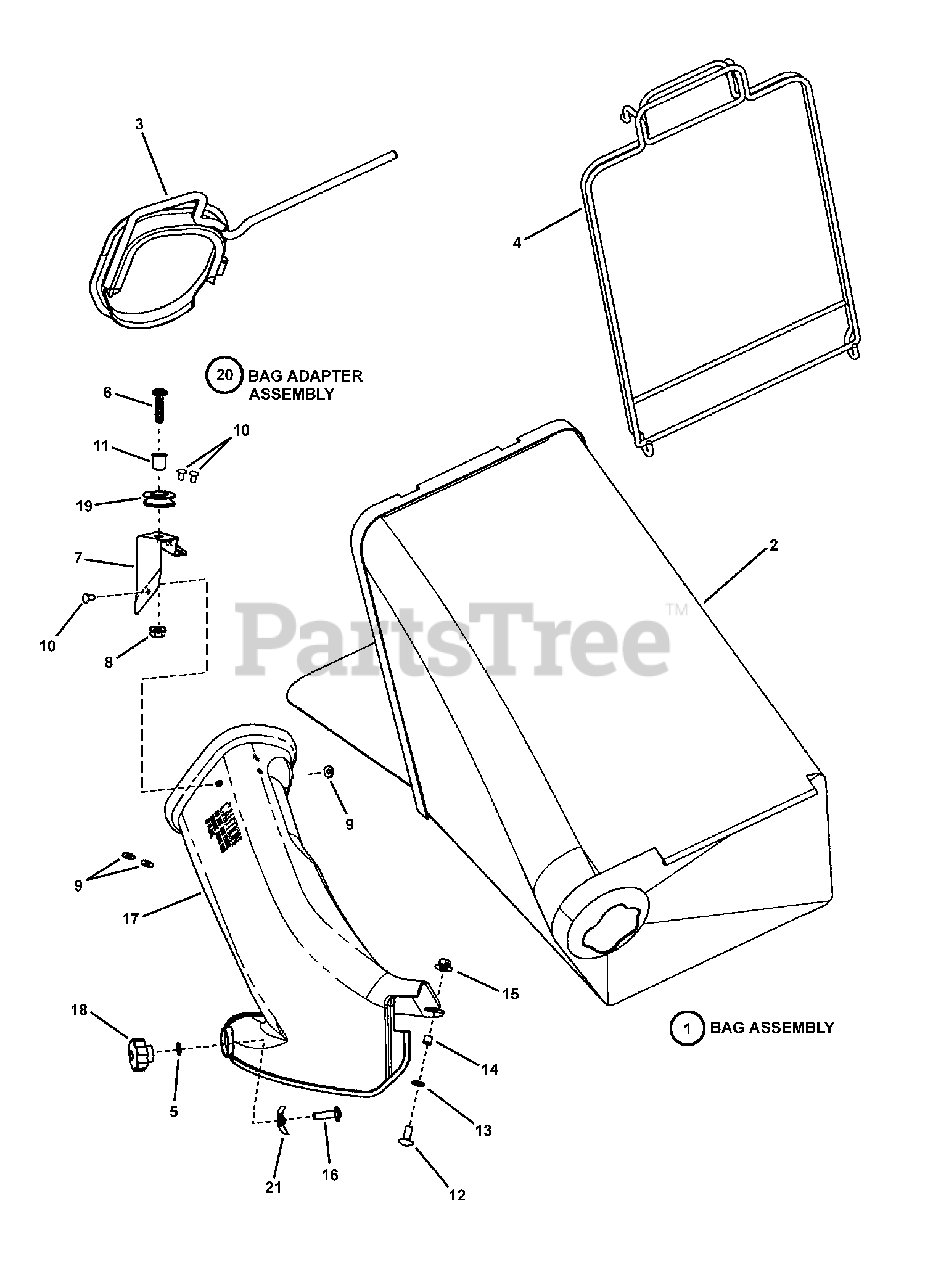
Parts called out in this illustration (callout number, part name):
1	BAG ASSEMBLY (Door)
2	GRASS BAG (Door w/silver letters)
3	CONNECTOR, Bag
4	ASSEMBLY, Bag Wire (12") 21S
5	WASHER, 5/16" Internal/External
6	SCREW, 5/16-18 x 1-1/4" Pan Head Machine
7	BRACKET, Rope Pulley
8	NUT, 5/16-18 Hex Flange Lock, GR 5
9	WASHER, 15/32" Flat
10	RIVET
11	BUSHING, Flange, .381 x .625 x .62
12	BOLT, 5/16-18 x 3/4" Short Square Neck Carriage, GR 5
13	BOLT RETAINER, 5/16- Black
14	SPACER, .316 x .375 x .300/.310
15	NUT, 5/16-18 Large Flange Hex Center Lock
16	SCREW, 5/16-18 x 5/8" Cross Recess Pan Head
17	ADAPTER, Bag
18	KNOB, Fluted (5/16-18 thread)
19	PULLEY, Nylon
20	ASSEMBLY, Bag Adapter
21	NUT, 5/16-18 Speed
